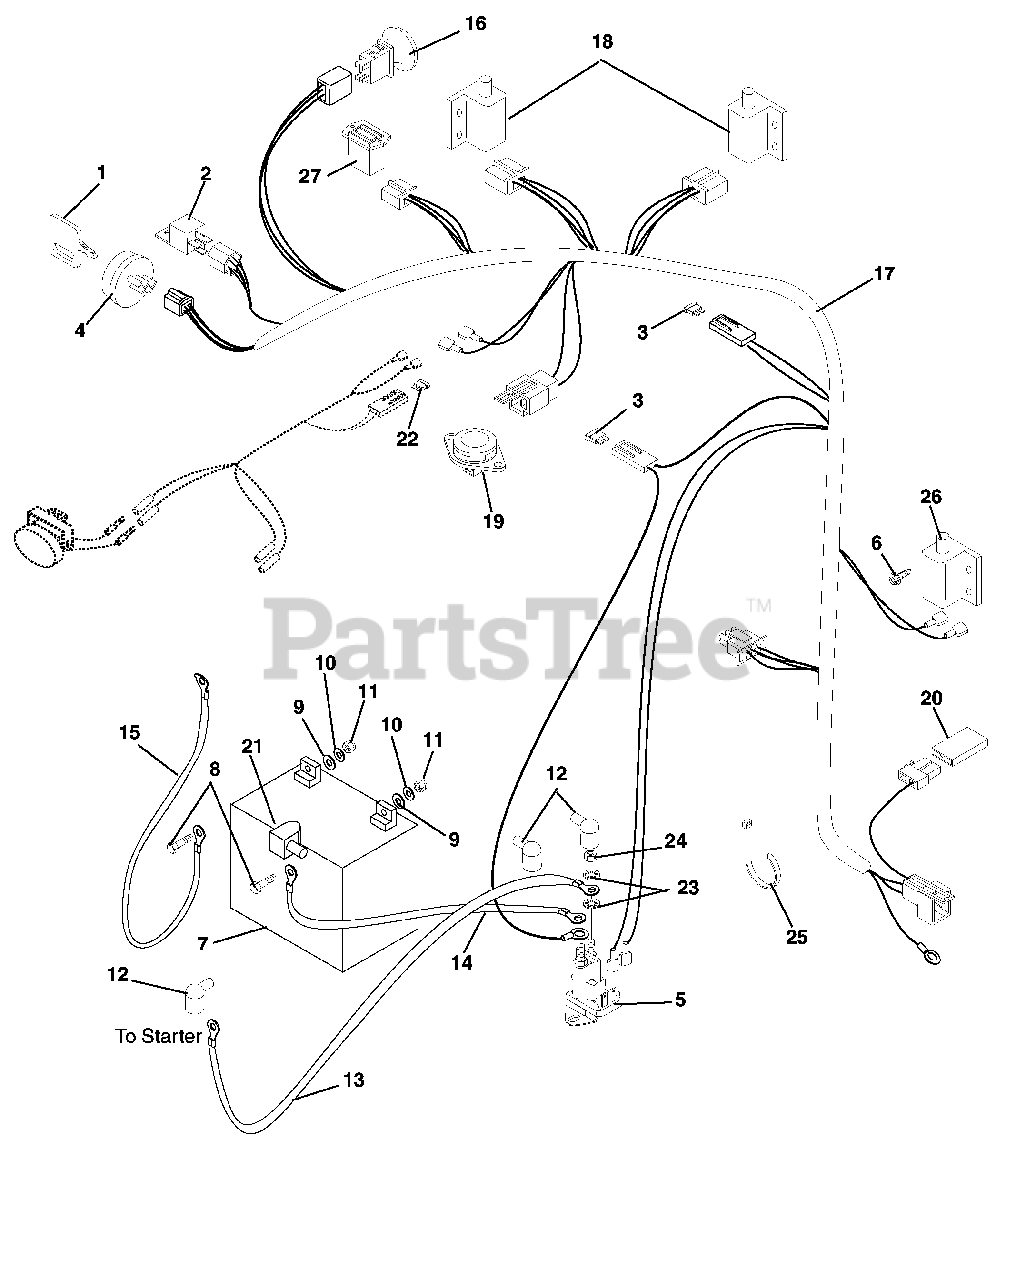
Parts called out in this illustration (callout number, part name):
1	Key with Cap
2	Relay
3	Fuse, 25 AMP
4	Key Switch
5	Solenoid (044)
6	Screw, Tapping 10- 24 x .50 Hex Washer Head
7	Battery, Filled
8	Bolt, Hex .25-20 x .75 Grade 5
9	Washer, Flat Steel .281 x .62 x .065
10	Washer, Locking .25 x .062 Regular
11	Nut, Hex .25-20
12	Boot, Eyelet Terminal (044)
12	Boot, Eyelet Terminal (046, 48, 50)
13	Starter Cable 22"
14	Starter Cable 13" (044)
15	Ground Cable
16	Switch, Clutch With Retainer
17	Wire Harness, Zoom 6 Pin
18	Switch, Double Pole N.O./N.O.
19	Switch, Snap Mounting (N.O.)
20	Diode, Connector Shell
21	Insulator
22	Fuse, 10 AMP
23	Washer, Locking .31 (044)
24	Nut, Jam .31-24 (044)
25	Cable Tie
26	Switch, Interlock NC
27	Hour Meter
